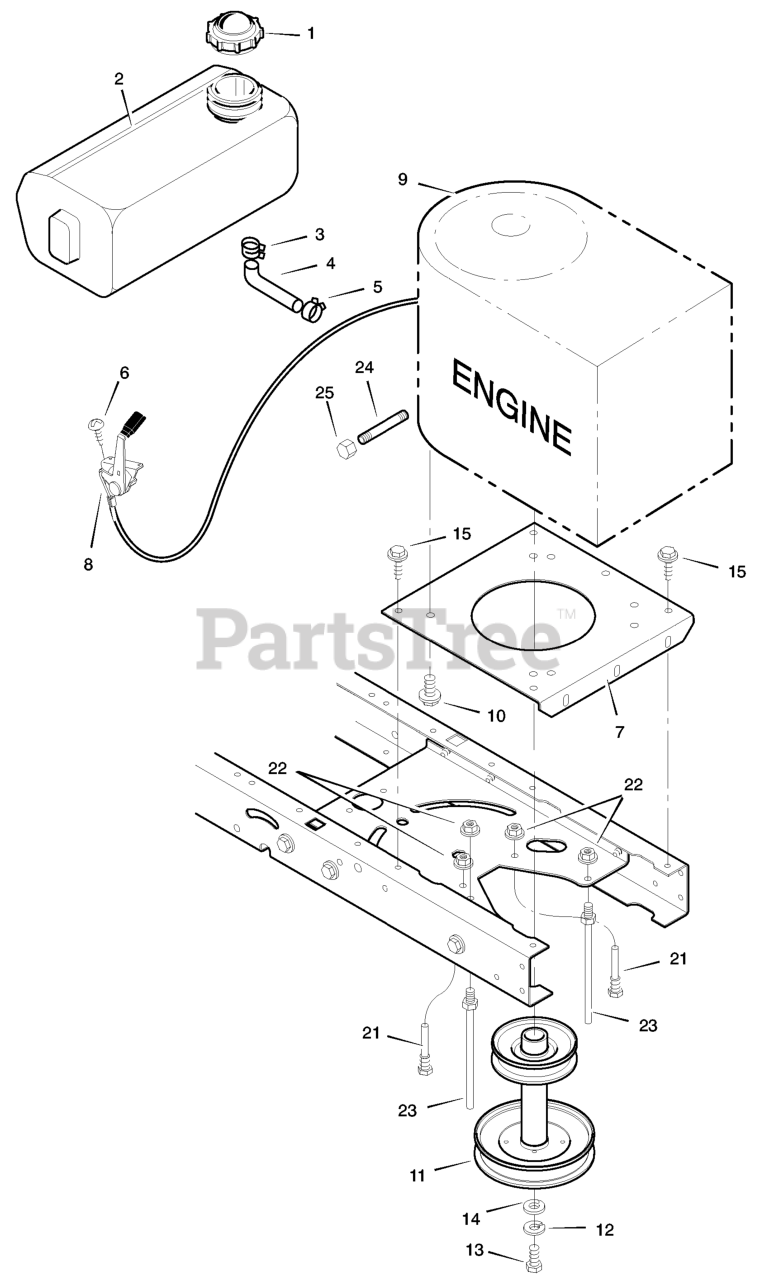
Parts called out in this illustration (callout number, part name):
1	Fuel Cap
2	Fuel Tank
3	Hose Clamp
4	Fuel Line (must cut to length)
5	Hose Clamp
7	Plate, Engine
8	Throttle Control
9	Engine
10	Bolt, Engine Mount
11	STACK PULLEY ASSEMBLY
12	Lockwasher
13	Bolt, Hex
21	Guide, Belt
22	Nut, Flange
23	Guide, Belt
24	Pipe, Oil Drain
25	Cap, Oil Drain
